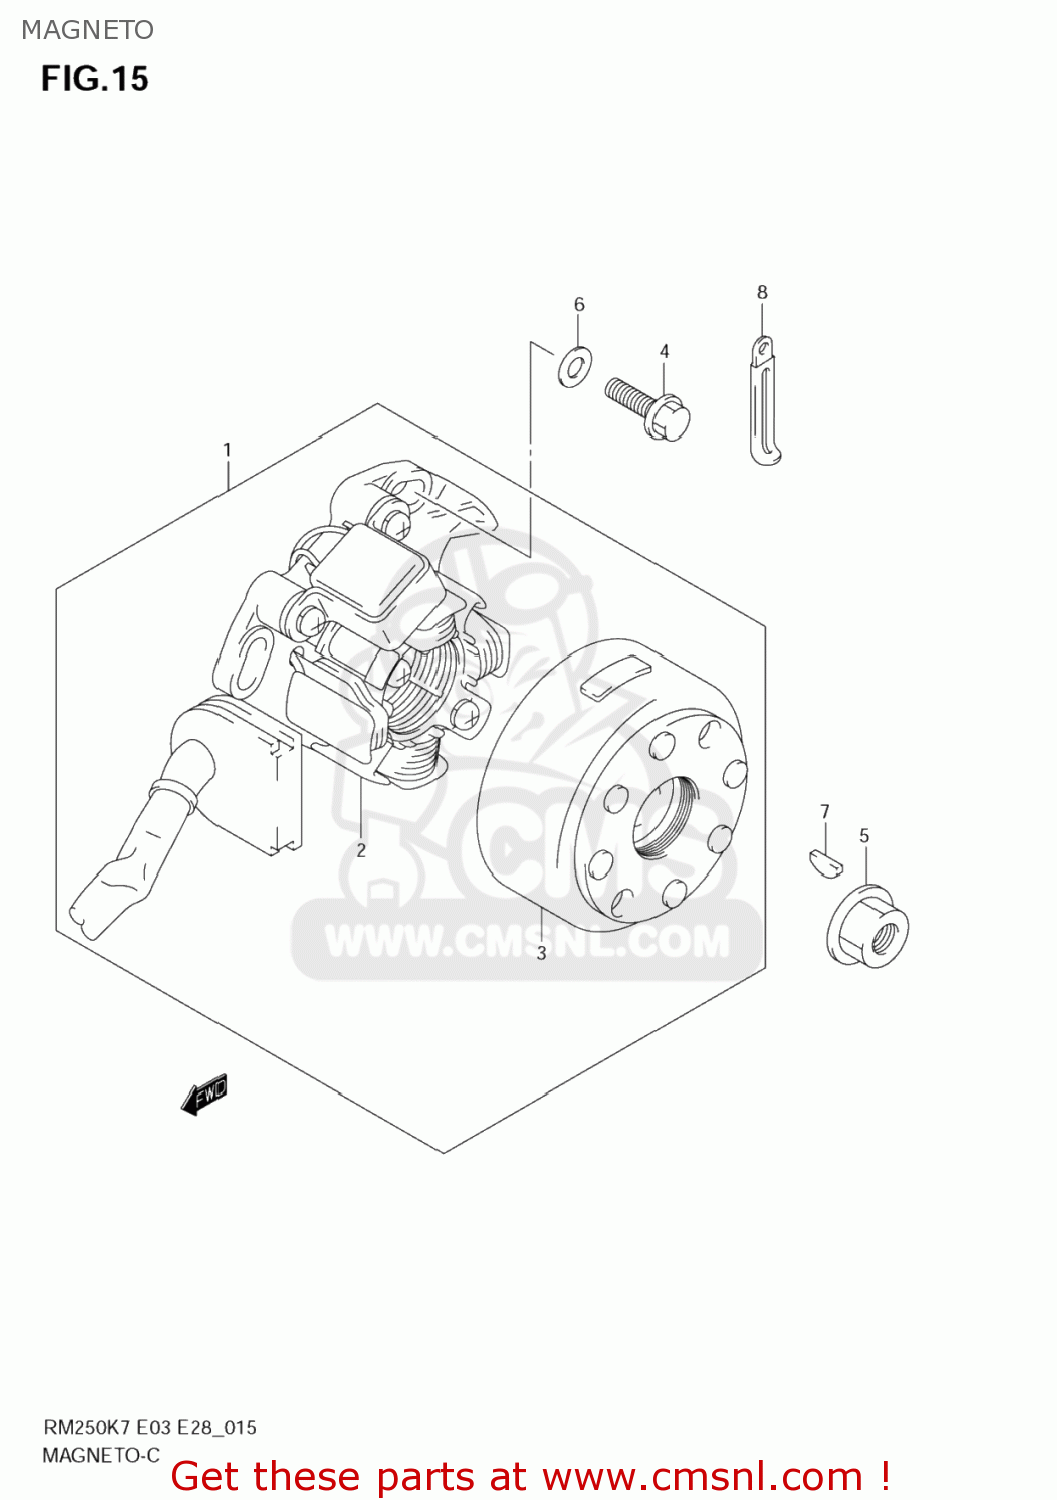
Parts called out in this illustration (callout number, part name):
1	MAGNETO ASSY
2	STARTER ASSY
3	ROTOR ASSY
4	BOLT
5	NUT
6	WASHER
7	KEY
8	CLAMP(L:80)
